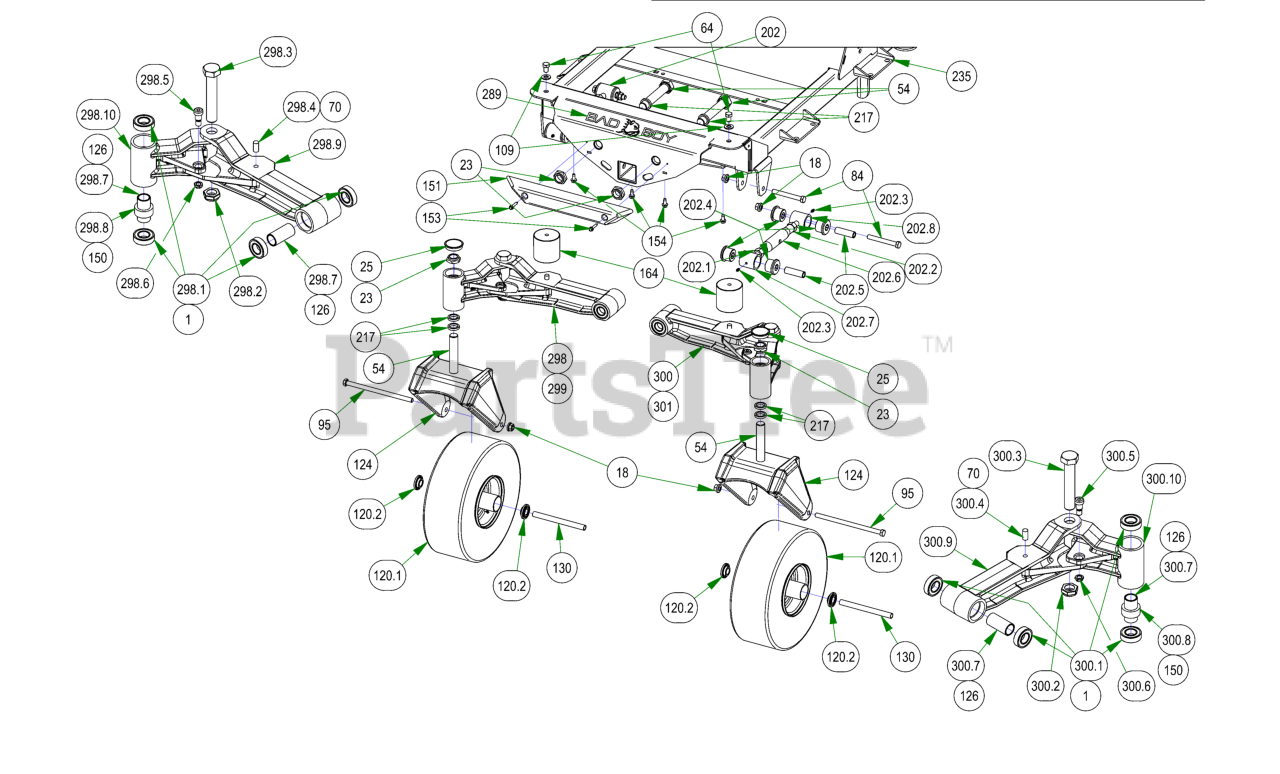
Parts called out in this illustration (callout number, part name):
1	1641 BEARING W/2 CONTACT RUBBER SEALS
18	1/2-13 NYLON INSERT FLANGE LOCKNUT ZINC
23	1"-14 NYLON INSERT JAM LOCKNUT ZINC
25	2017 Bearing Cover
54	1"-14 X 5-1/2 HEX CAP SCREW (GR.8) ZINC YELLOW
64	1/2-13 X 3/4 HEX CAP SCREW (GR.5) ZINC
70	1/2-13 x 1" Stud
84	1/2-13 X 4 HEX CAP SCREW (GR.8) ZINC YELLOW
95	1/2-13 X 9 HEX CAP SCREW (GR.5) ZINC
109	1/2 SAE FLAT WASHER (1-1/16" OD) GR.8 ZINC YELLOW
120	2019 15x6.00-6 Non Pneumatic Black Front Assembly
120.1	15x6-6 Tire Only
120.2	1-3/4" Bearing-Large Bore Front Rim
124	2020 R Series Cast Front Fork
126	2016 Front Bearing Spacer
130	Front Wheel Spanner
150	Rubber Stabilizer (Front Forks) [R series]
151	2017 XP Bumper
153	1/4-14 X 1-1/2 HEX WASHER UNSLOT TEK/3 ZINC
154	5/16-18 X 3/4 HEX WASHER SLOT (F) TCS ZINC
164	Vibration Mount-Blue Dot
202	Turnbuckle
202.1	11/16-12 Hex Nut-2015 Toplink
202.2	11/16-12 Lefthand Hex Nut-Topl
202.3	1/4" Press in Grease Fitting
202.4	Polyeurethane Bushing
202.6	2015 Outlaw Toplink Body
202.7	2015 Outlaw Toplink RH End
202.8	2015 Outlaw Toplink LH End
217	1.02 ID X 1.38 OD X .250 THK SPACER ZINC
235	2023 Rogue Frame - Painted
289	Flying Bulldog Front Bumper Decal
298	2022 61/72 Rogue/Renegade Front Suspension Asy RH
298.1	1641 BEARING W/2 CONTACT RUBBER SEALS
298.2	1" Fine Thread 1/2 Nylock Nut
298.3	1"-14 X 5-1/2 HEX CAP SCREW (GR.8) ZINC YELLOW
298.4	1/2-13 x 1" Stud
298.5	5/8 X 5/8 SOCKET SHOULDER BOLT ZINC YELLOW
298.6	1/2-13 NYLON INSERT JAM LOCKNUT ZINC
298.7	2016 Front Bearing Spacer
298.8	Rubber Stabilizer (Front Forks) [R series]
298.9	INNER RH FRONT AXLE
298.10	OUTER FRONT ARM RH
299	2019 Front I-Beam Left - Black
300	2022 61/72 Rogue/Renegade Front Suspension Asy LH
300.1	1641 BEARING W/2 CONTACT RUBBER SEALS
300.2	1" Fine Thread 1/2 Nylock Nut
300.3	1"-14 X 5-1/2 HEX CAP SCREW (GR.8) ZINC YELLOW
300.4	1/2-13 x 1" Stud
300.5	5/8 X 5/8 SOCKET SHOULDER BOLT ZINC YELLOW
300.6	1/2-13 NYLON INSERT JAM LOCKNUT ZINC
300.7	2016 Front Bearing Spacer
300.8	Rubber Stabilizer (Front Forks) [R series]
300.9	INNER FRONT ARM LH
300.10	CAST OUTER ARM LH
301	R.H. I-BEAM ARM - Black
